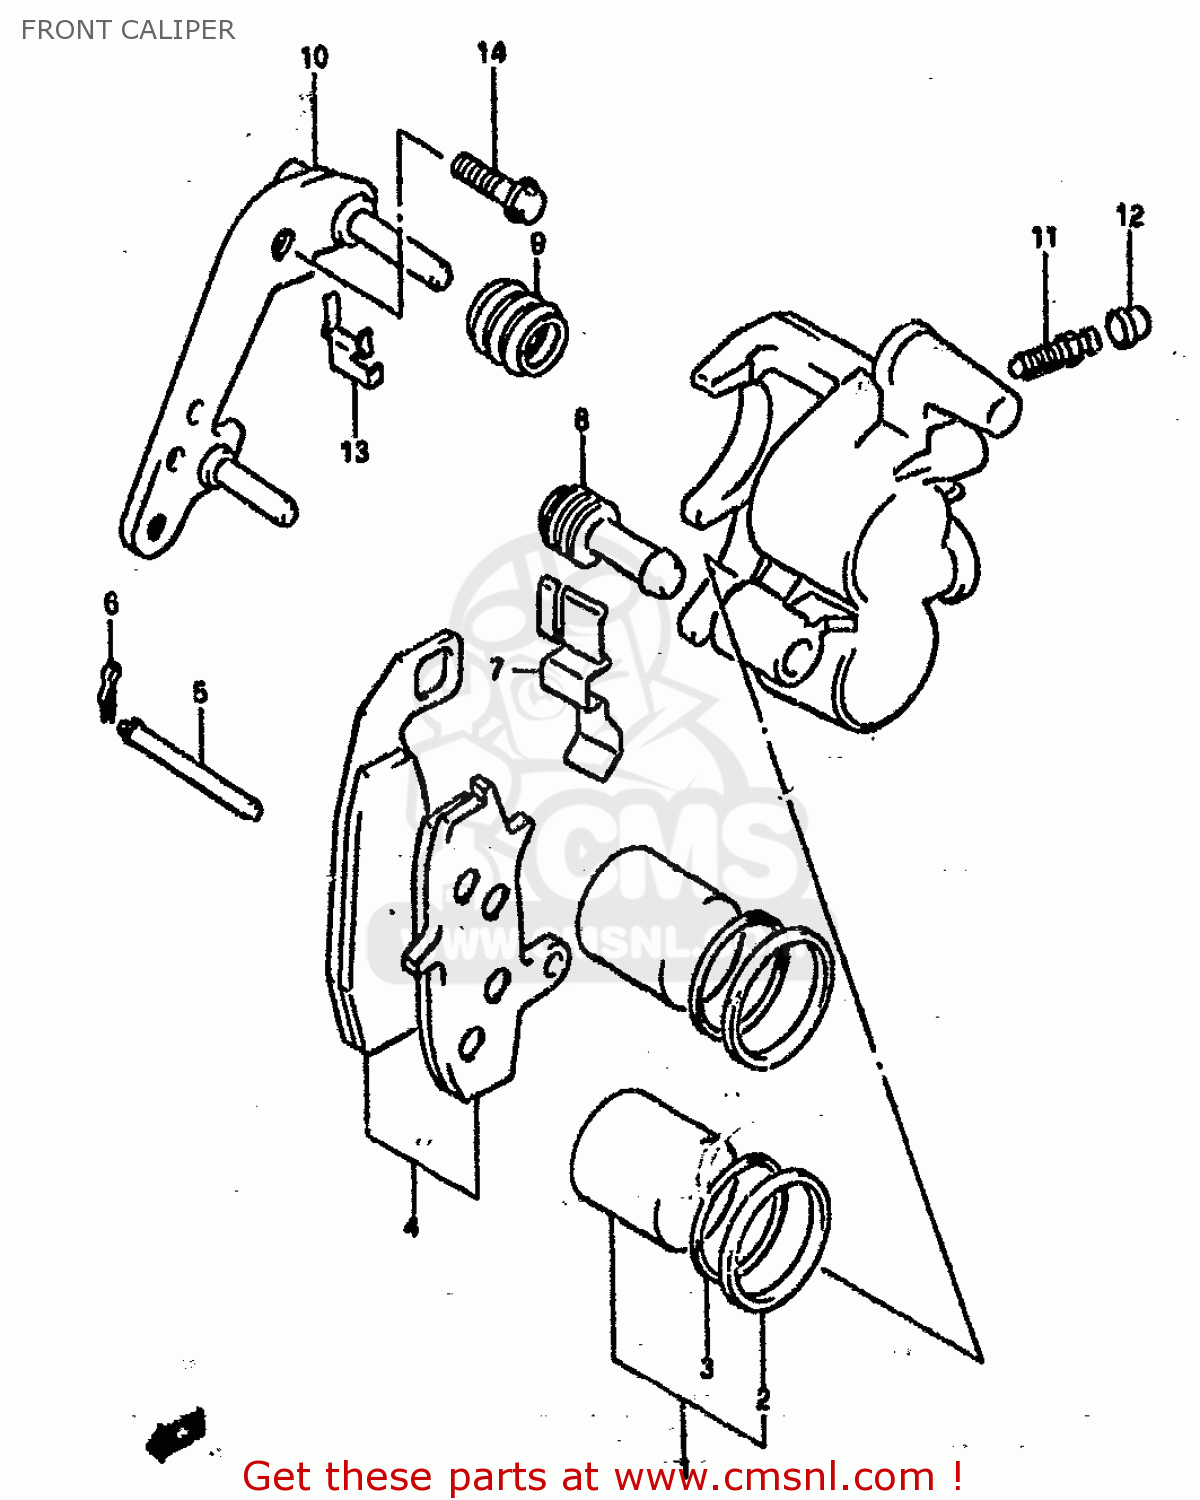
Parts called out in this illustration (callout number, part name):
1	PISTON SET
2	SEAL,PISTON
3	SEAL,WIPER
4	PAD SET (NAS)
5	PIN,PAD
6	CLIP,PAD PIN
7	SPRING,PAD
8	INSULATOR,AXLE
9	BOOT,AXLE
10	BRACKET
11	BLEEDER
12	CAP,BREATHER
13	GUIDE,PAD
14	BOLT
